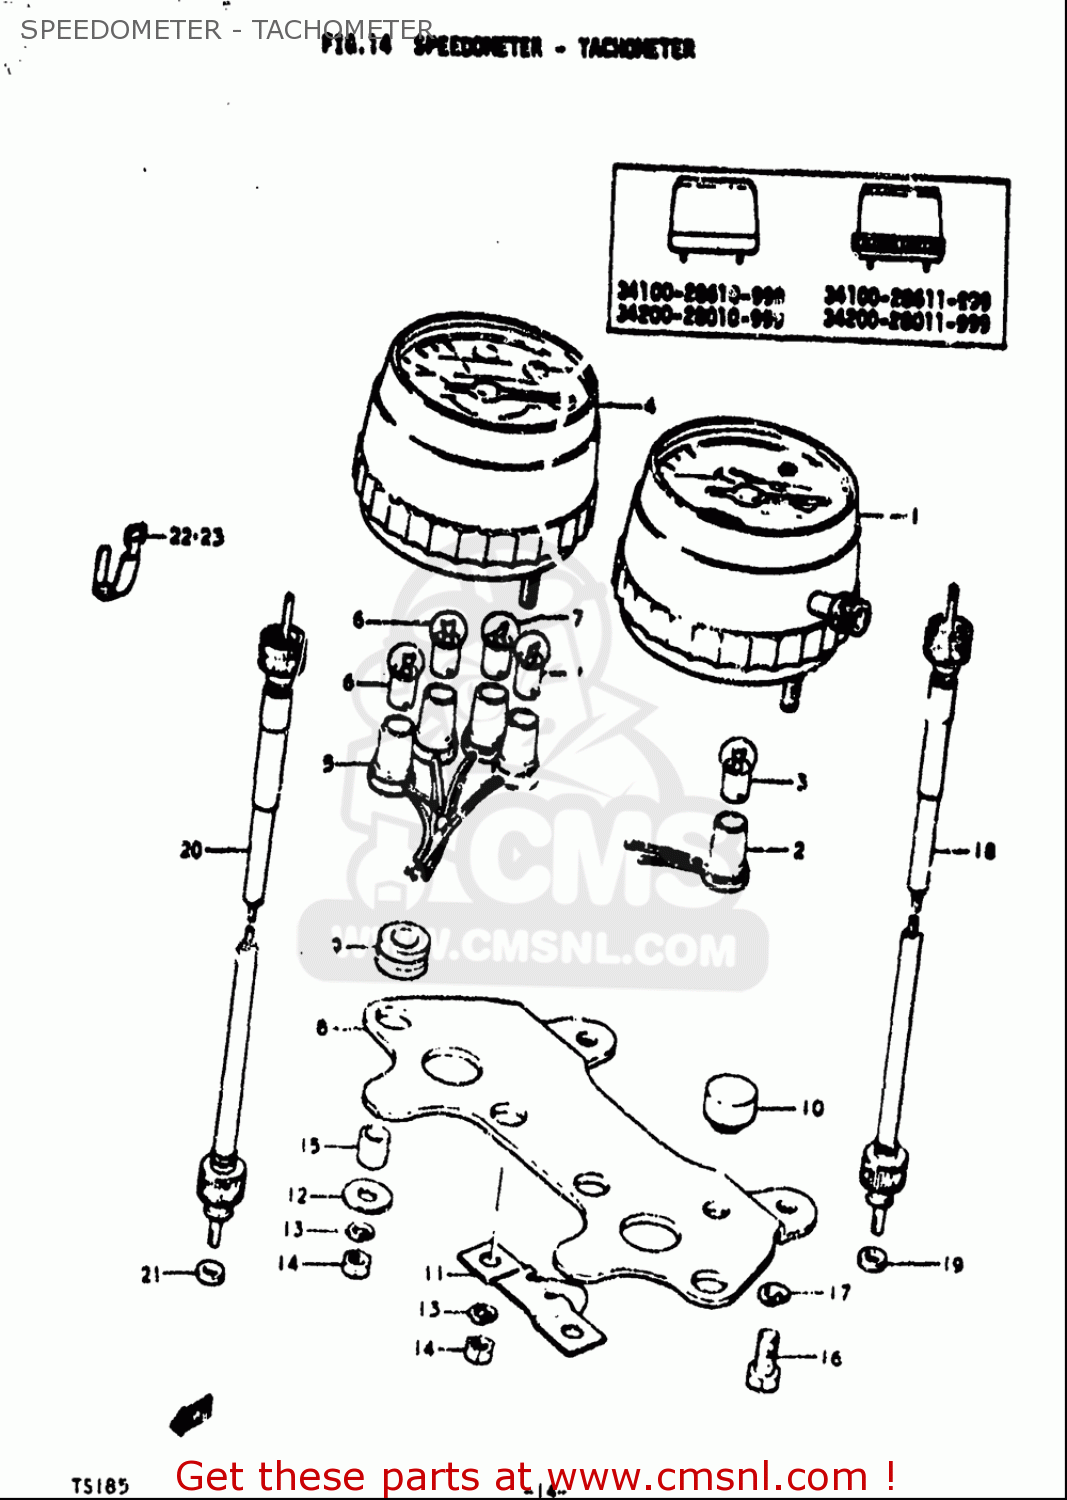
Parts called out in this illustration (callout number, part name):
3	BULB(6V/3W)
6	BULB(6V/3W)
7	BULB(6V1.7W,STANLEY,A61A)
9	CUSHION
12	WASHER(5.5X16X1.2)
13	WASHER,LOCK
14	NUT
15	SPACER,METER NO.2
16	BOLT
17	WASHER,LOCK
18	CABLE ASSY,SPEEDOMETER
19	SEAL,OIL METER CABLE
20	CABLE ASSY,TACHOMETER
21	SEAL,OIL SPEEDOMETER CABLE
22	CLAMP
23	CLAMP
